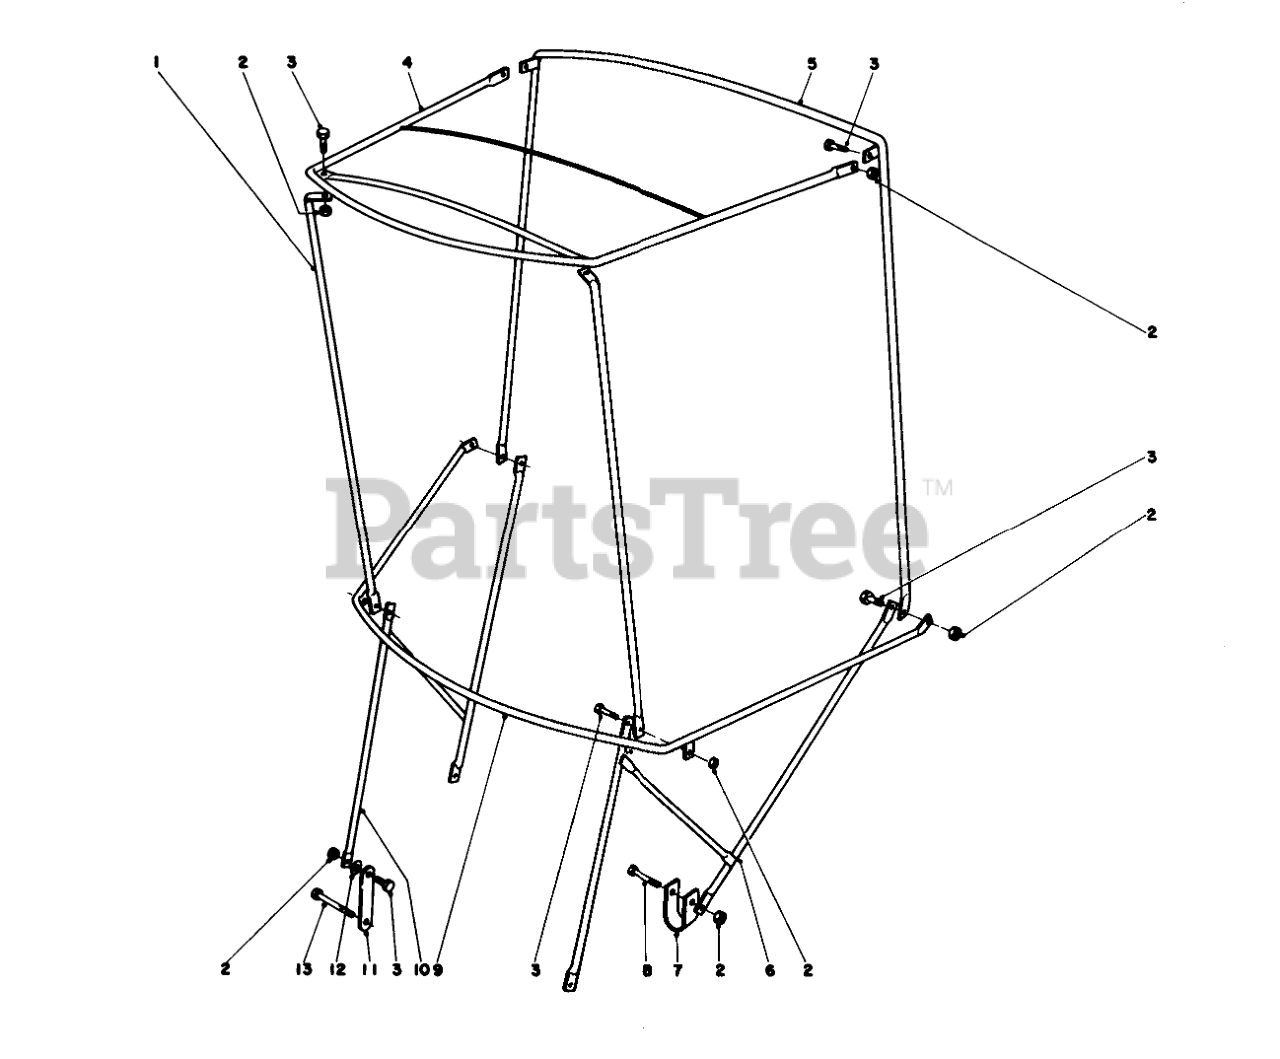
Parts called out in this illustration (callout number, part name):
2	NUT-LOCK
3	SCREW-HH
4	FRAME-TOP
5	BOW-VERTICAL, REAR
6	Attaching Bracket, L.H.
7	U CLAMP
8	SCREW-HH
9	BOW-CURVED
10	Attaching Bracket, R.H.
11	Mounting Strap
12	WASHER-LOCK/EXT
13	SCREW-HH
